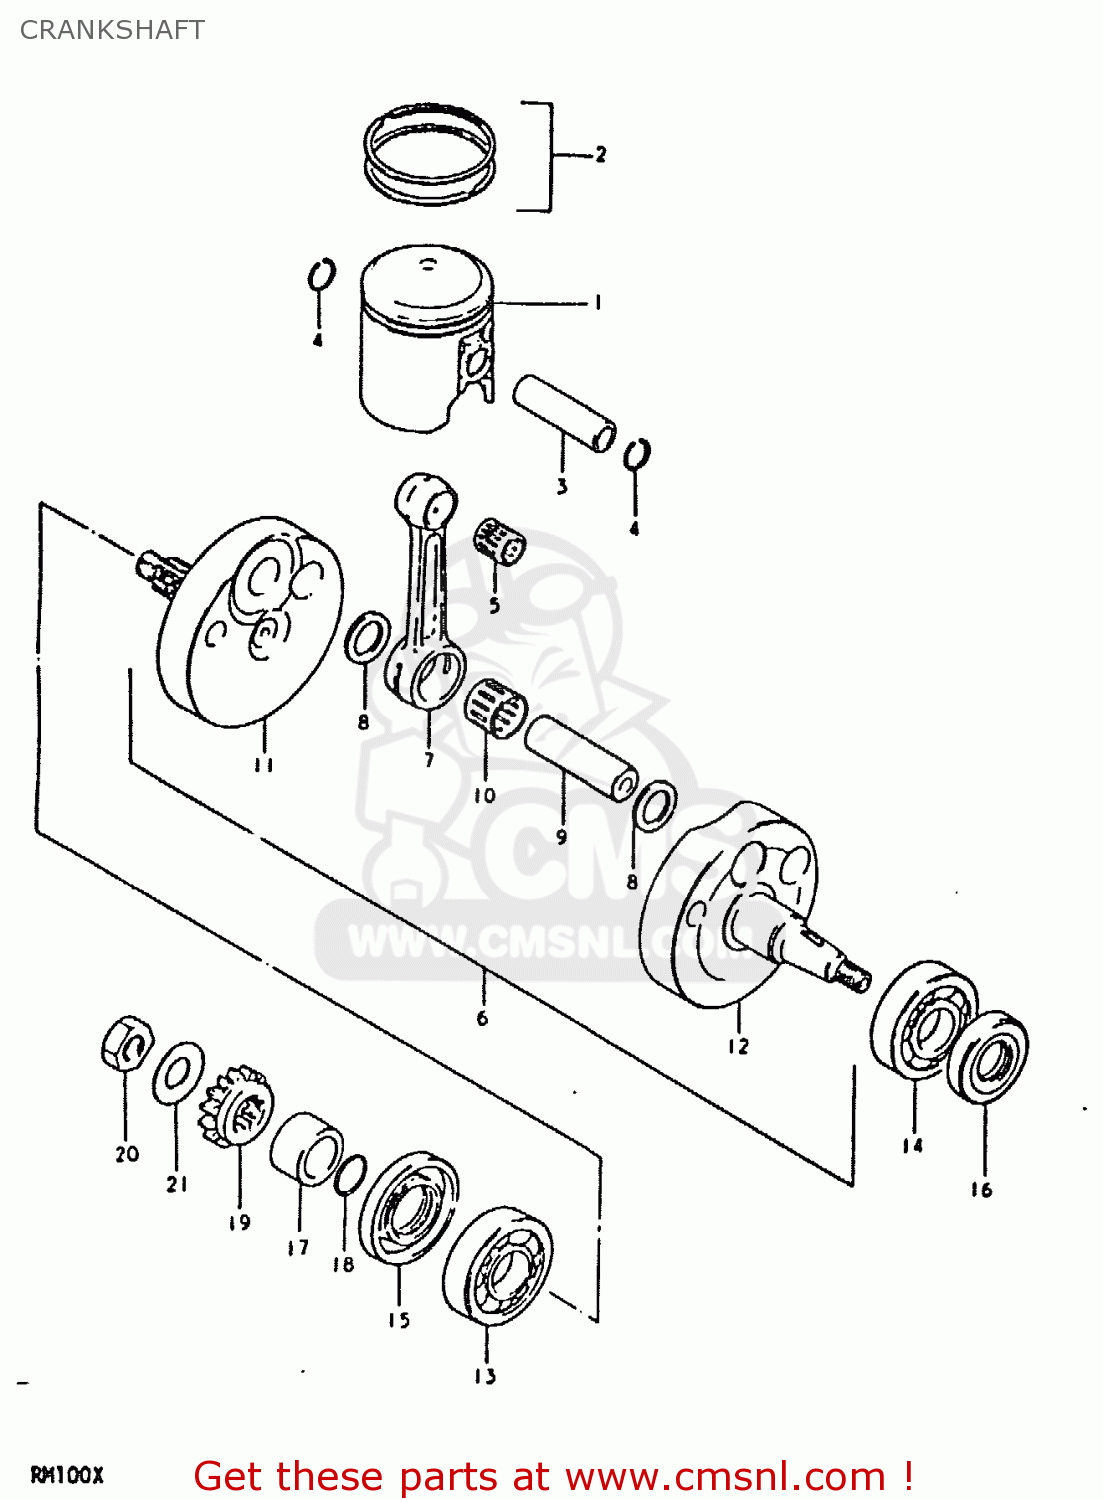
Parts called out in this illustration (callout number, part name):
1	PISTON (50.00MM)
2	RING SET,PISTON
3	PIN,PISTON 14MM
4	RING,SNAP 14MM
5	BEARING
6	CRANKSHAFT ASSEMBLY
7	CONNECTING ROD
8	WASHER(19X32X1)
9	PIN,CRANK
10	BEARING(19X25X16)
11	CRANKSHAFT
12	CRANKSHAFT,LEFT
13	BEARING
14	BEARING
15	SEAL,OIL(29X47X8)
16	OIL SEAL
17	SPACER (20X29X20.5)
18	O RING(D:2.4,ID:19.8)
19	GEAR,PRIMARY DRIVE
20	NUT
21	WASHER
